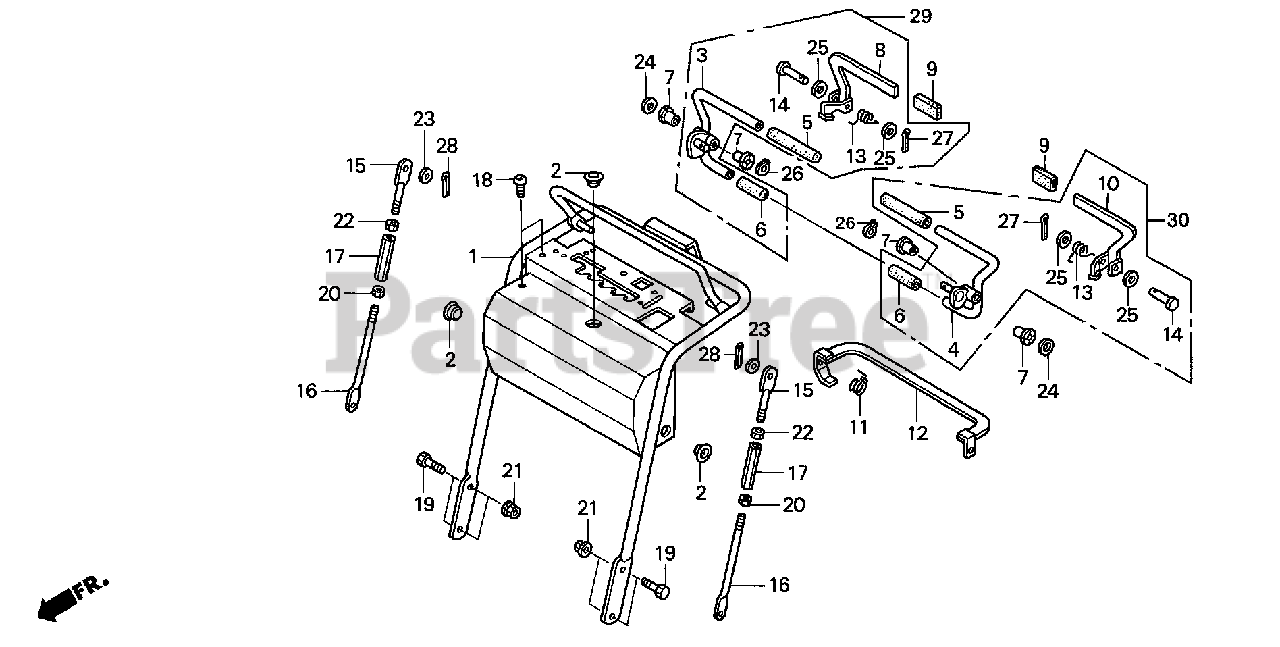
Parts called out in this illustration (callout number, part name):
1	PIPE, HANDLE
3	LEVER, R. CLUTCH
4	LEVER, L. CLUTCH
5	GRIP, CLUTCH LEVER (UPPER)
6	GRIP, CLUTCH LEVER (LOWER)
7	BUSH, CLUTCH LEVER
8	LEVER, R. PRESENCE
9	CAP, PRESENCE LEVER
10	LEVER, L. PRESENCE
11	SPRING, REVERSE PRESENCE RETURN
12	LEVER, REVERSE PRESENCE
13	SPRING, PRESENCE RETURN
14	PIN, CLEVIS (3/16X1-3/4)
14	PIN, CLEVIS (1/4X1 3/4)
15	ROD A, CLUTCH
16	ROD B, CLUTCH
17	JOINT, CLUTCH ROD
18	SCREW (5/16"-18)
19	BOLT, HEX. (3/8-16X1")
20	NUT, JAM (1/2-20) (NOT AVAILABLE)
21	NUT, WHIZ-LOCK (3/8"-16)
22	NUT, JAM (1/2"-20) (LEFT)
23	WASHER, FLAT (3/8")
24	WASHER (9/16")
25	WASHER, FLAT (#10)
25	WASHER, FLAT (1/4)
26	CIRCLIP (1/2")
27	PIN, COTTER (5/64"X1/2")
28	PIN, COTTER (1/8X3/4")
29	KIT, R. CLUTCH LEVER
30	KIT, L. CLUTCH LEVER
